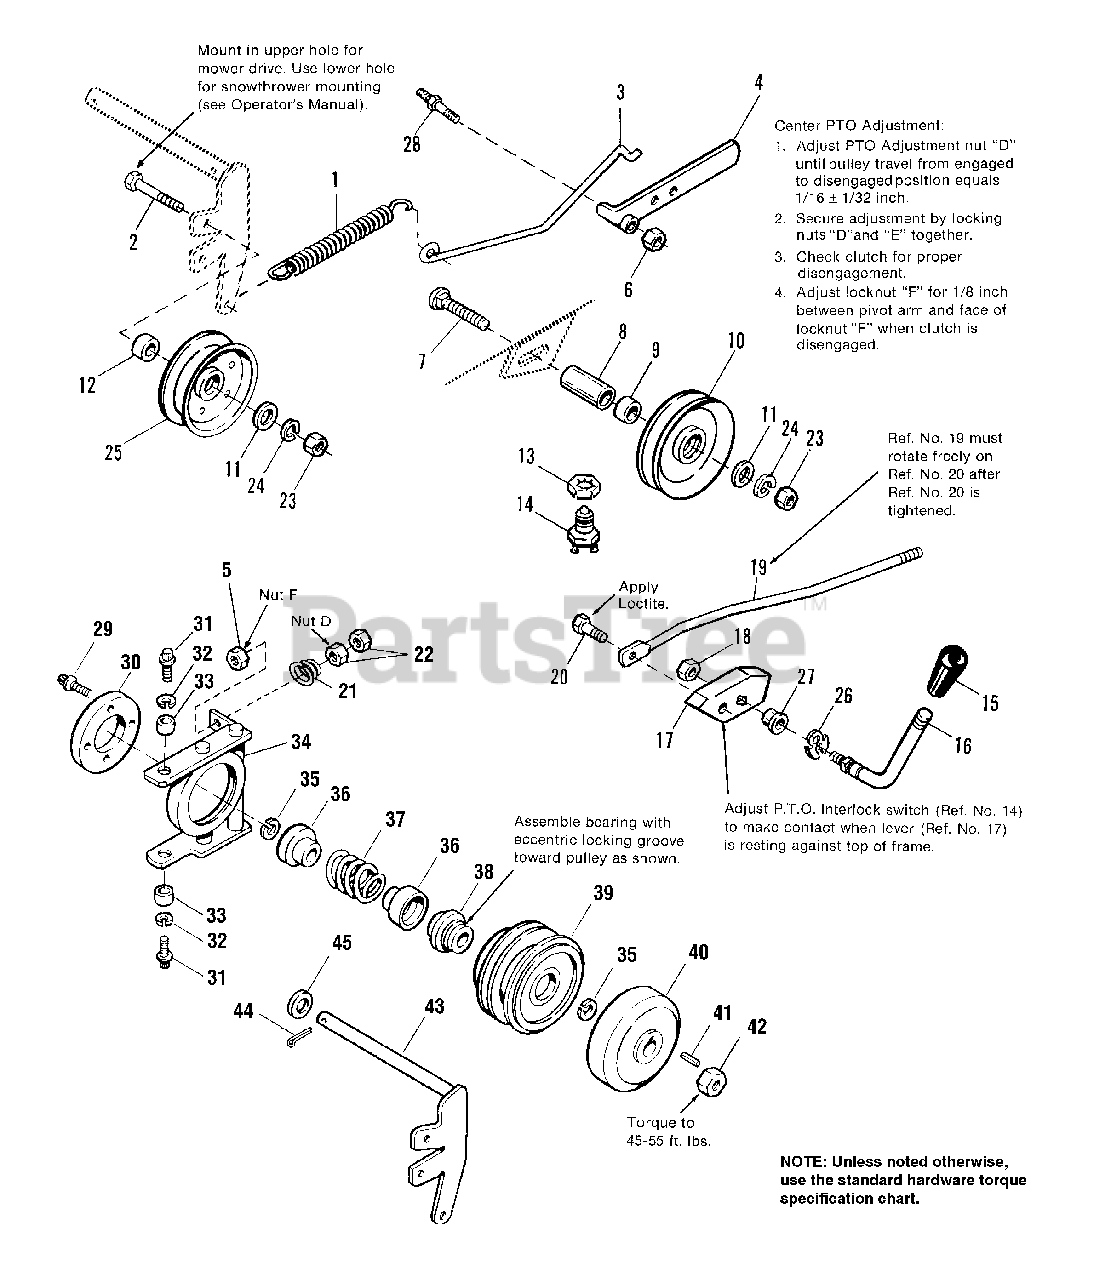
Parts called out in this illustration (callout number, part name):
1	SPRING, Tension
2	CAPSCREW, Hex Hd, 3/8-16 x 2
3	ROD, Tension
4	HANDLE ASSEMBLY
5	LOCKNUT, Hex, 5/16-18
6	LOCKNUT, Hex, 7/16-14
7	CARRIAGE BOLT, 3/8-16 x 1-3/4
10	PULLEY ASSEMBLY, w/ Bearings
11	WASHER, Plain, 3/8
14	SWITCH, Interlock
16	HANDLE, PTO, Clutch
18	LOCKNUT, Hex, 3/8-16
19	ROD ASSEMBLY, Control
20	CAPSCREW, Hex Hd, 5/16-18 x 7/8
22	NUT, Hex, Full, 5/16-18
23	NUT, Hex, Full, 3/8-16
24	LOCKWASHER, 3/8
25	PULLEY, Idler
26	KLIPRING, 1/2
29	CAPSCREW, Socket Hd., 1/4-20 x 5/8
30	DISC, Brake
31	CAPSCREW, Thread Forming
32	LOCKWASHER, 5/16
34	PIVOT ASSEMBLY
35	RING, Retaining
36	GUIDE, Spring
38	BEARING ASSEMBLY
40	PLATE ASSEMBLY, Clutch
41	KEY
42	LOCKNUT, Hex, 3/4-16
43	ARM ASSEMBLY, Pivot
44	PIN, Cotter, 3/16 x 1-1/2
